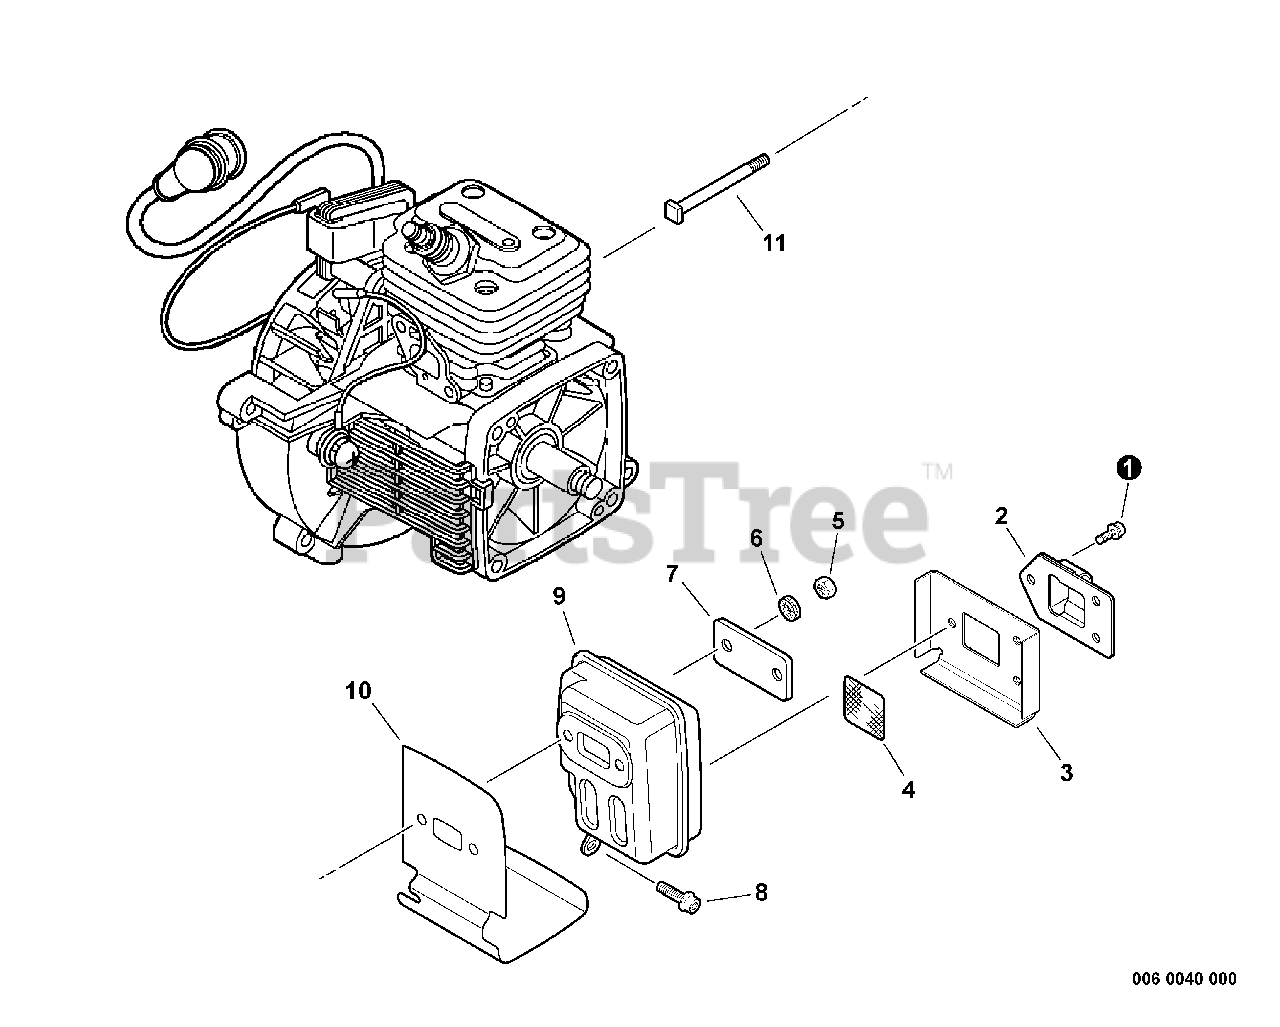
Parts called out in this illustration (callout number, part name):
1	SCREW 4×12
2	GUIDE, EXHAUST
3	GASKET, EXHAUST
4	SCREEN, SPARK ARRESTER
5	NUT M5
7	PLATE, EYE
8	BOLT 5×16
9	MUFFLER
10	HEAT SHIELD, EXHAUST
11	BOLT 5×60
